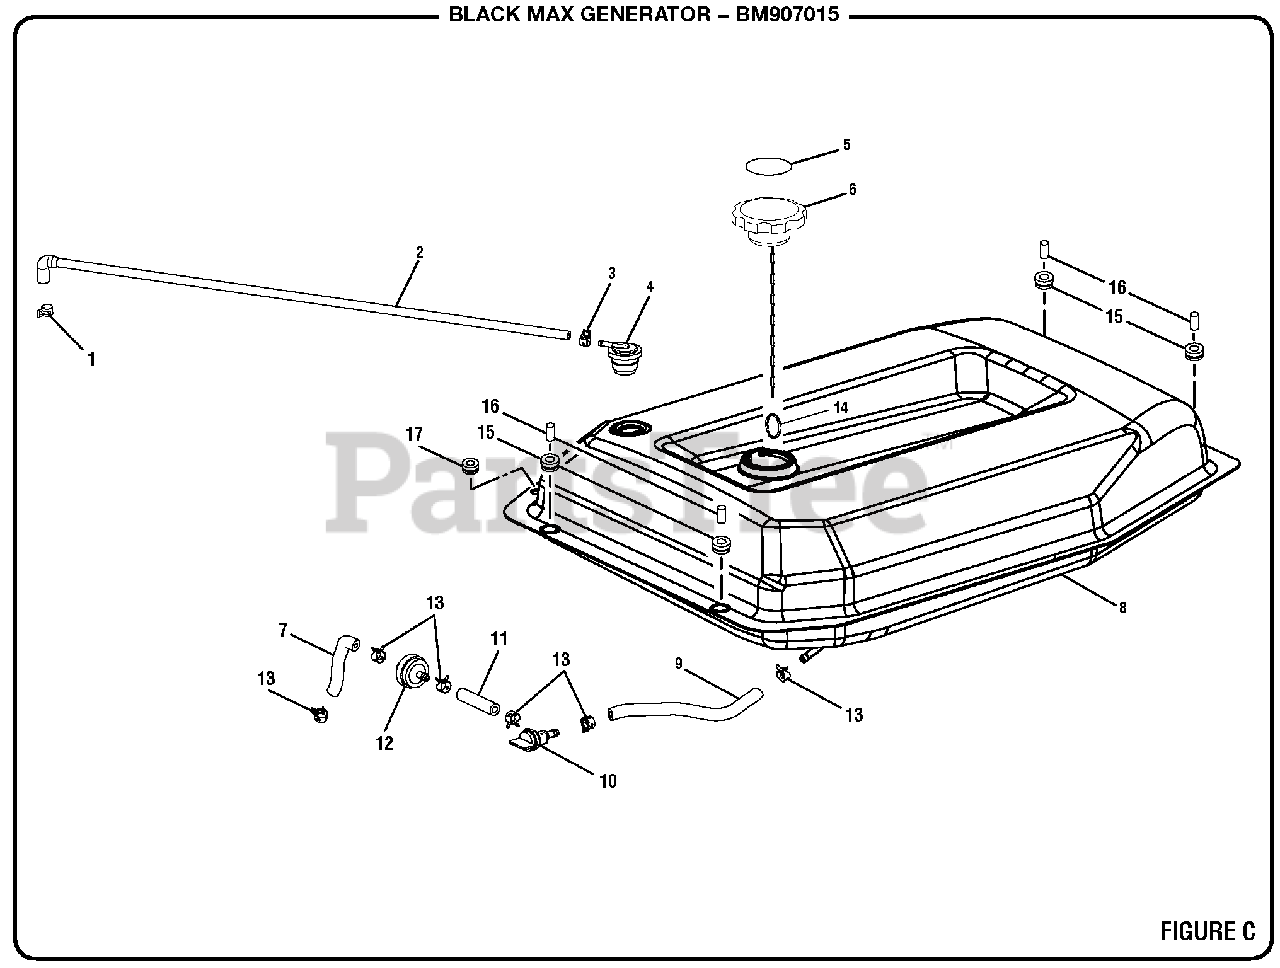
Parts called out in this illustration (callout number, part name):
1	Fuel Line Clamp (10.3 mm)
2	Vapor Hose (590 mm and 30 mm)
3	Fuel Line Clamp (3/8 in.)
4	Vapor Vent
5	Fuel Cap/Stabilizer Label (English)
7	Fuel Hose (185 mm)
8	Fuel Tank
9	Fuel Hose (175 mm)
10	Fuel Valve
11	Fuel Hose (55 mm)
12	Fuel Filter
13	Fuel Line Clamp (1/2 in.)
14	Ring Clip
17	Fuel Hose Protector
